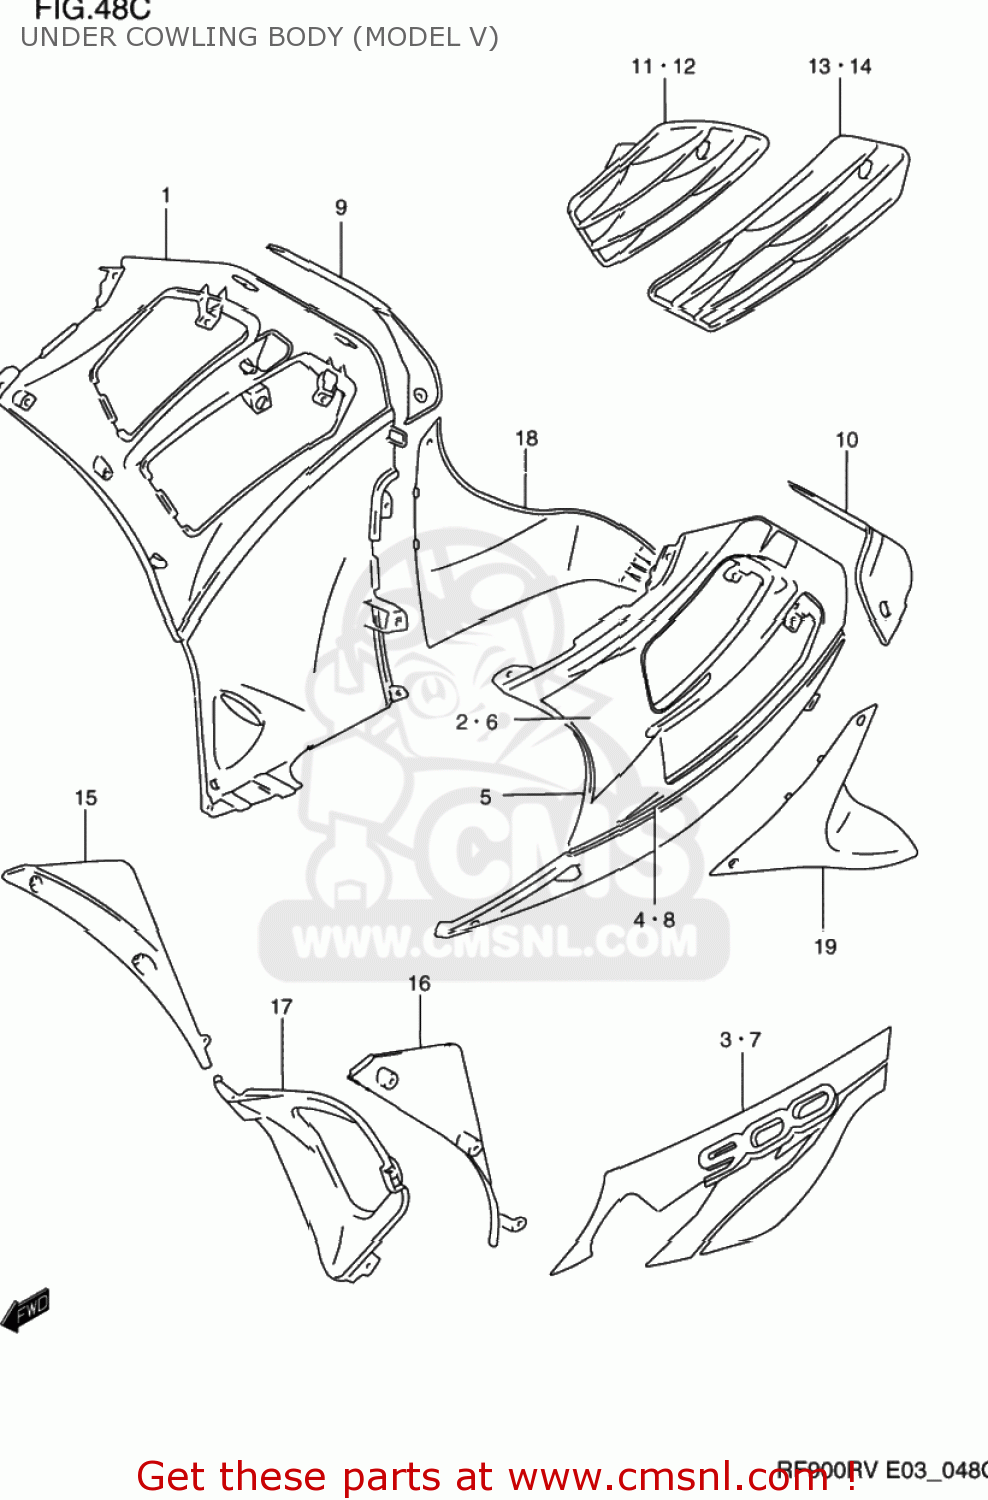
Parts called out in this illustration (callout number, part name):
1	COWLING ASSY,UNDER,R
2	TAPE SET,COWLING,UNDER
3	TAPE SET,COWLING,UNDER
4	TAPE,UNDER COWL,R
5	COWLING ASSY,UNDER,L
6	TAPE SET,COWL UNDER UPR,L
7	TAPE SET,COWL UNDER LWR,L
8	TAPE,UNDER COWL,L
9	PANEL,UNDER,R
10	PANEL,UNDER,L
11	COVER,UNDER COWL UPR,R
12	COVER,UNDER COWL UPR,L
13	COVER,UNDER COWL LWR,R
14	COVER,UNDER COWL LWR,L
15	COWLING,UNDER INNER,R
16	COWLING,UNDER INNER,L
17	COWLING,UNDER CTR
18	COWLING,UNDER RR,R
19	COWLING,UNDER RR,L
